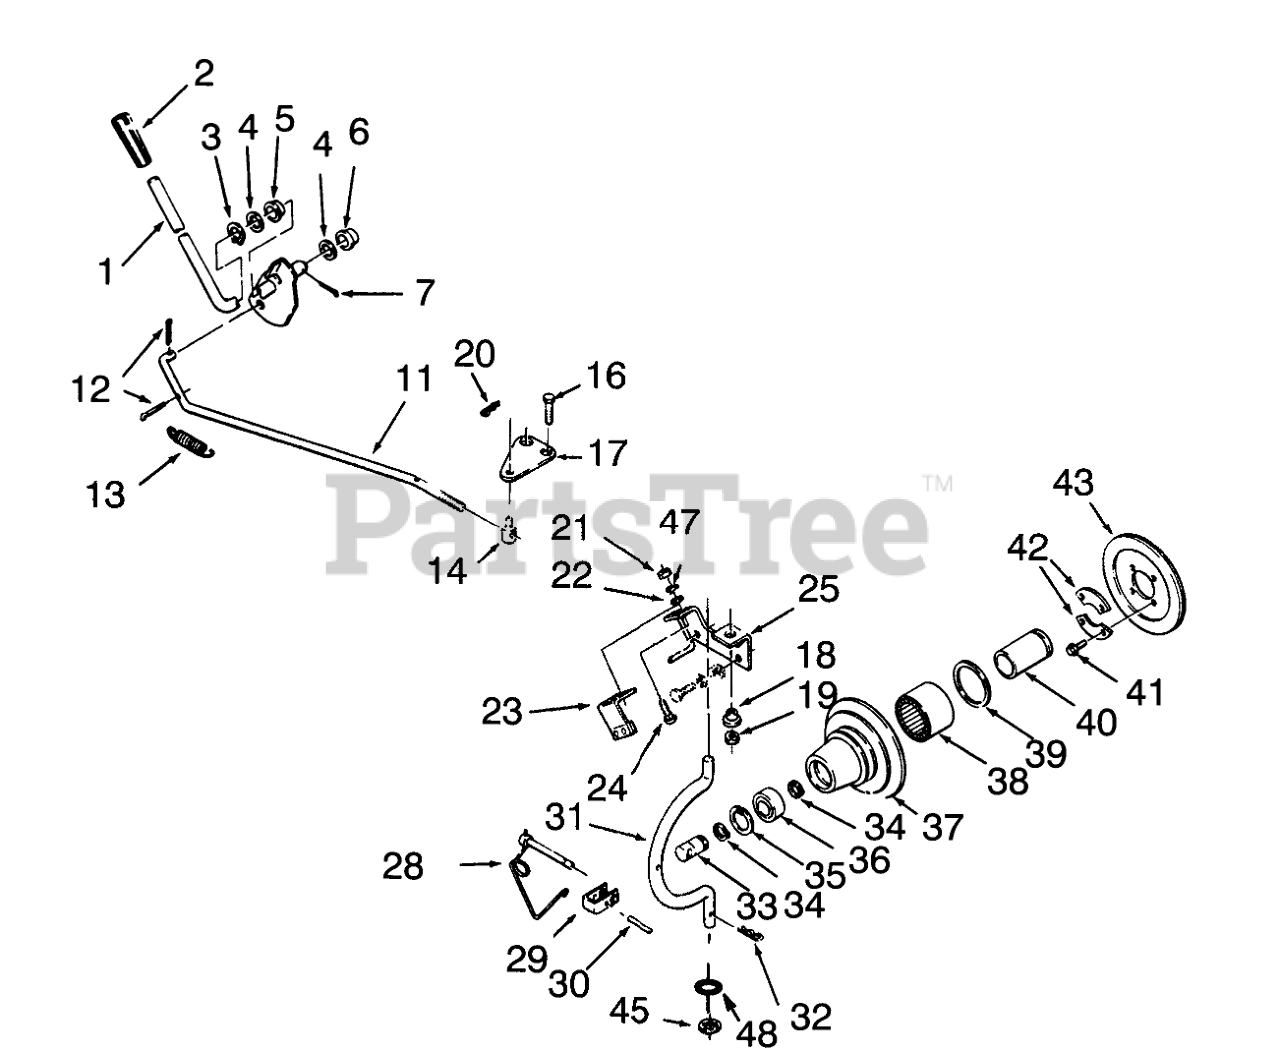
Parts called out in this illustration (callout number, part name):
1	ASSY PTO CLUTCH LEVE
2	GRIP
3	Grip Ring
4	SHIM-WASHER
5	BUSHING-NYLINER
6	NYLINER BUSHING
7	PIN-COTTER
11	ROD-PTO CLUTCH
12	PIN-COTTER
13	SPRING
14	TRUNNION
16	SCREW-HH
17	PLATE
18	SPACER-LIFT LINK
19	NUT-LOCK, NI
20	Hairpin Cotter
21	NUT-JAM
22	WASHER-FLAT
23	ASM-Bracket
24	SCREW-CARR
25	Bracket
28	LOCKING PIN ASM
29	CLEVIS
31	ROD-HOUSING
32	Hairpin
33	SHAFT-PTO
34	Ring-Snap
35	Ring-Snap
36	BEARING-BALL
37	Housing-Clutch
38	BRG-NEEDLE OPEN END
39	SEAL-OIL
40	RACE-BEARING
41	SCREW-HH
42	RETAINER
43	Facing-Clutch
45	RING-REINFORCED CIRC
47	WASHER-LOCK
48	WASHER-FLAT
